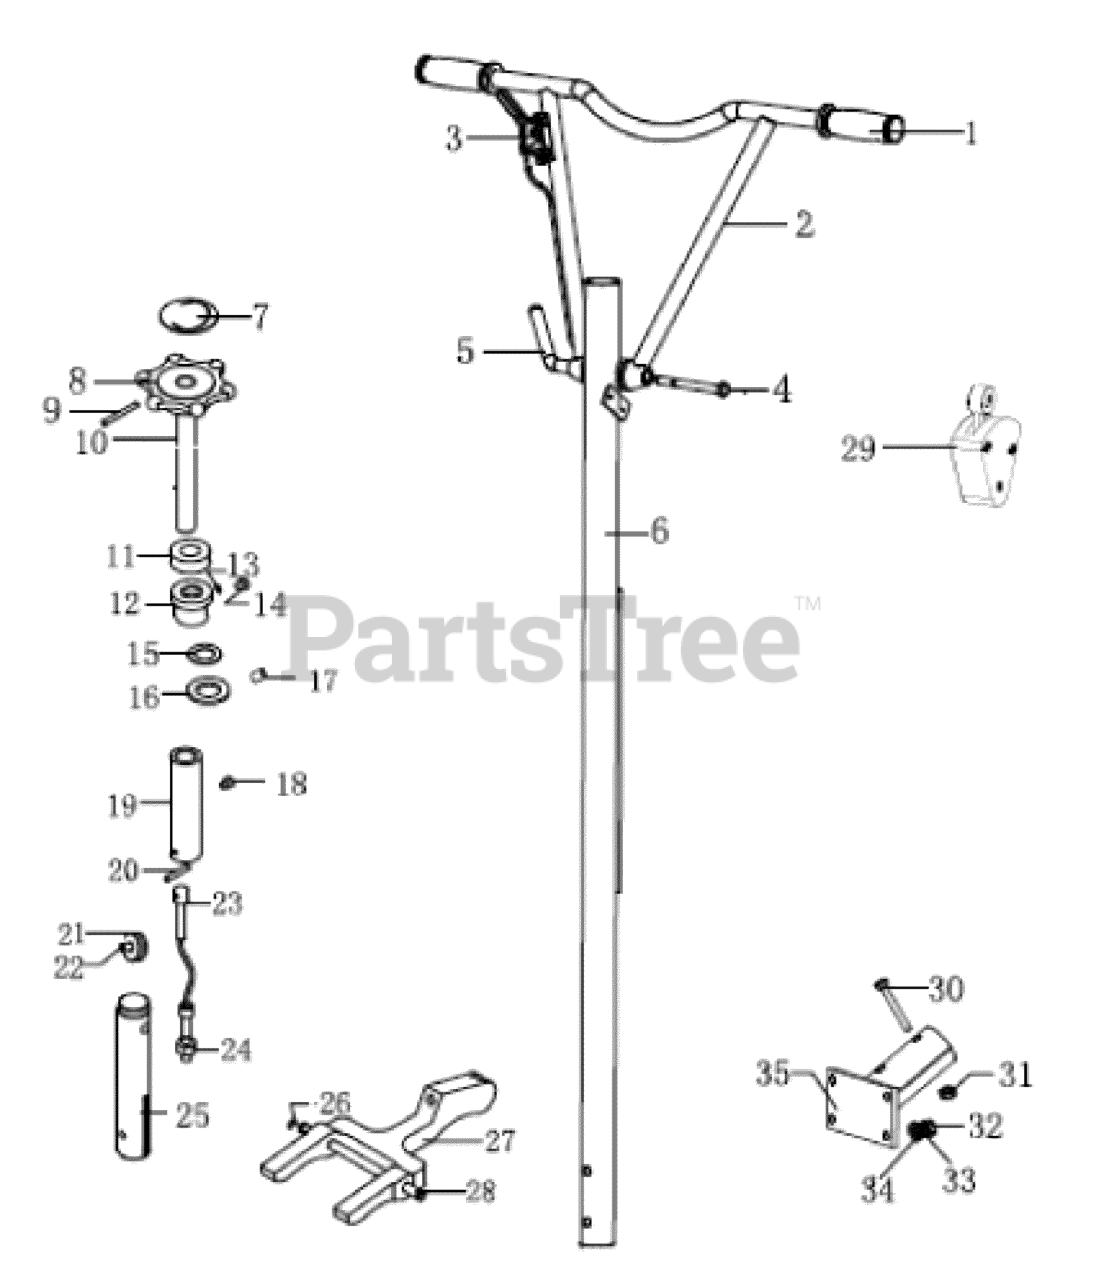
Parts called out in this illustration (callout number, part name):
1	GRIP, Handle, Rubber
2	HANDLE
3	THROTTLE ASSEMBLY
4	BOLT, M10 x 120
5	HANDLE, Locking
6	PIPE, Center Jointing
7	LABEL, Return Direction
9	SPRING PIN, 5 x 50
10	ROD, Adjust Screw
11	BEARING, Thrust
12	BUSHING
13	WASHER, Spring, d6
14	SCREW, Pan Head Cross Recess, M6 x 8
15	WASHER, Spring, Undee
16	WASHER
17	SCREW, Set, M8 x 10
18	SCREW, Set, M6 x 6
19	PIPE, Adjust Screw
20	SPRING PIN, 5 x 35
21	WHEEL, Roller
22	PIN, B8 x 38
23	TERMINAL, Steel Cable
24	NUT, M8
25	SHAFT, Roller Wheel
26	WASHER, Split, d8
27	SHIFTING YOKE
28	SHAFT, Shifting Yoke
29	STOPPING DEVICE ASSEMBLY
30	BOLT, M10 x 70
31	NUT, Lock, M10
32	NUT, M10
33	WASHER, Spring, 10
34	WASHER, Flat, d10
35	LINK, Handle
